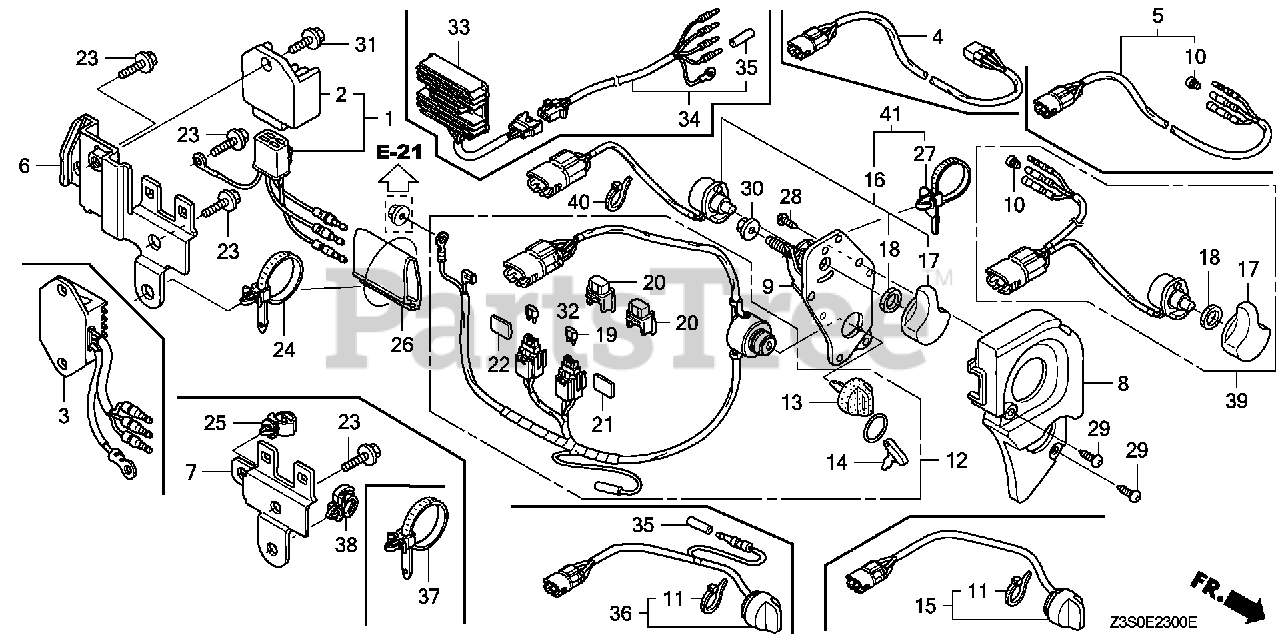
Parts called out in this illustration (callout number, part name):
4	SUB-WIRE HARNESS ASSY. (ENGINE SWITCH)
4	SUB-WIRE HARNESS ASSY. (SPEED VOLUME)
8	PANEL, CONTROL
29	SCREW, TAPPING (5X20)
